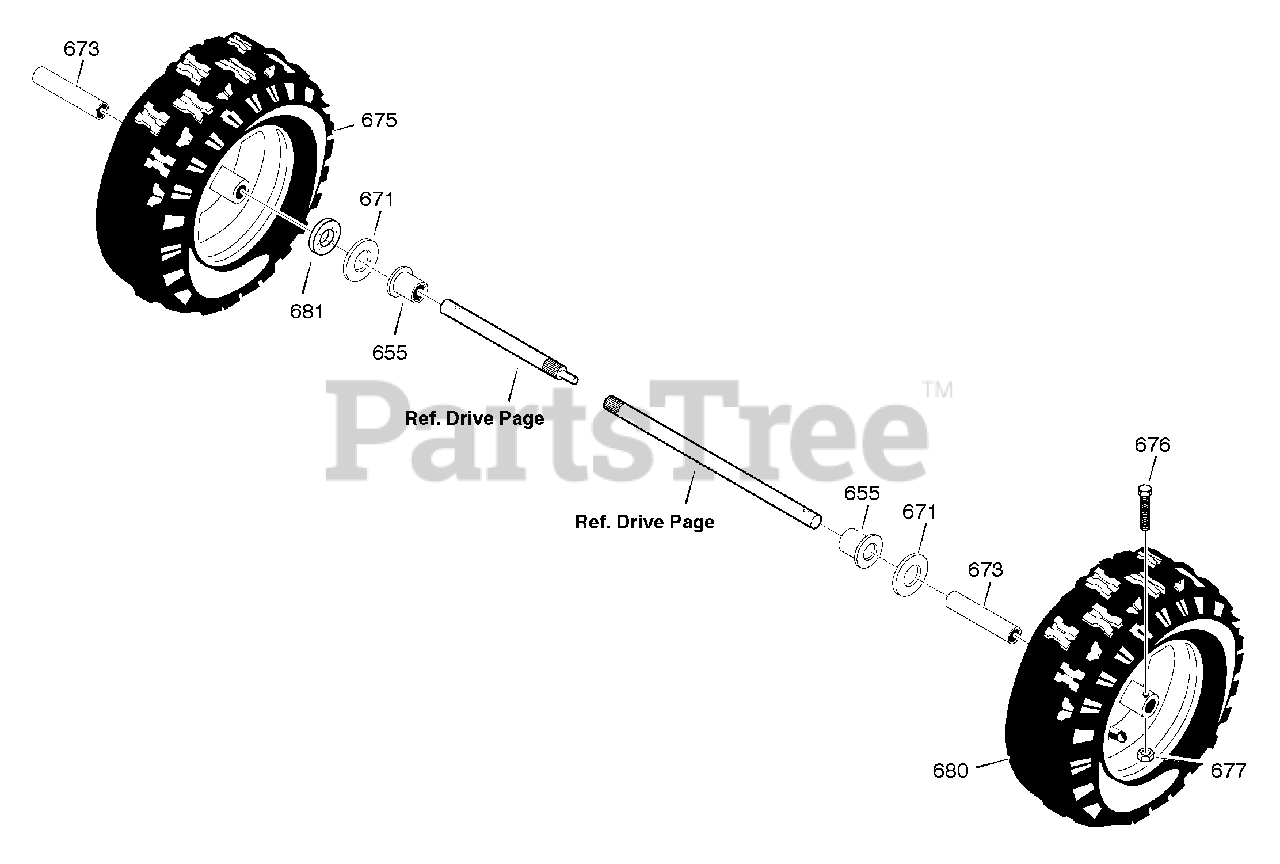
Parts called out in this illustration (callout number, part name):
655	BEARING, AXLE
671	FLATWASHER
673	BUSHING, WHEEL
675	TIRE & RIM, LEFT
676	SCREW, 1/4-20X1.75 HH
677	NUT, 1/4-20 HEX NYLOCK
680	TIRE & RIM, RIGHT
681	RETAINER
